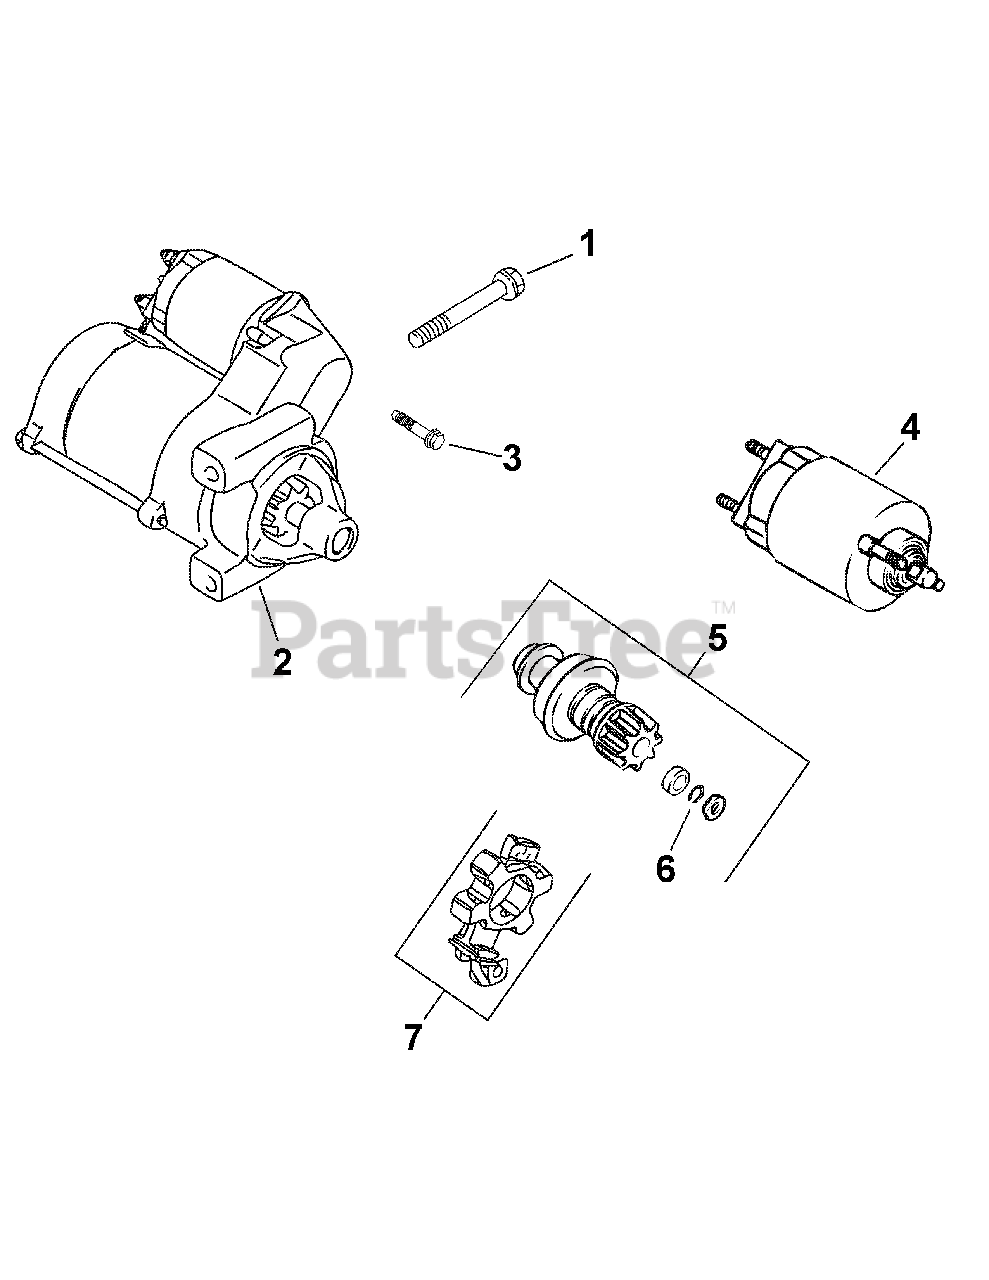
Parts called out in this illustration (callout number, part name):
1	Screw, hex flange M8x1.25x80
2	Starter, solenoid ass’y (Incl 3-7)
3	Screw, external torx hd.
4	Kit, solenoid (Includes 3)
5	Kit, starter pinion (Includes 6)
7	Brush, holder
